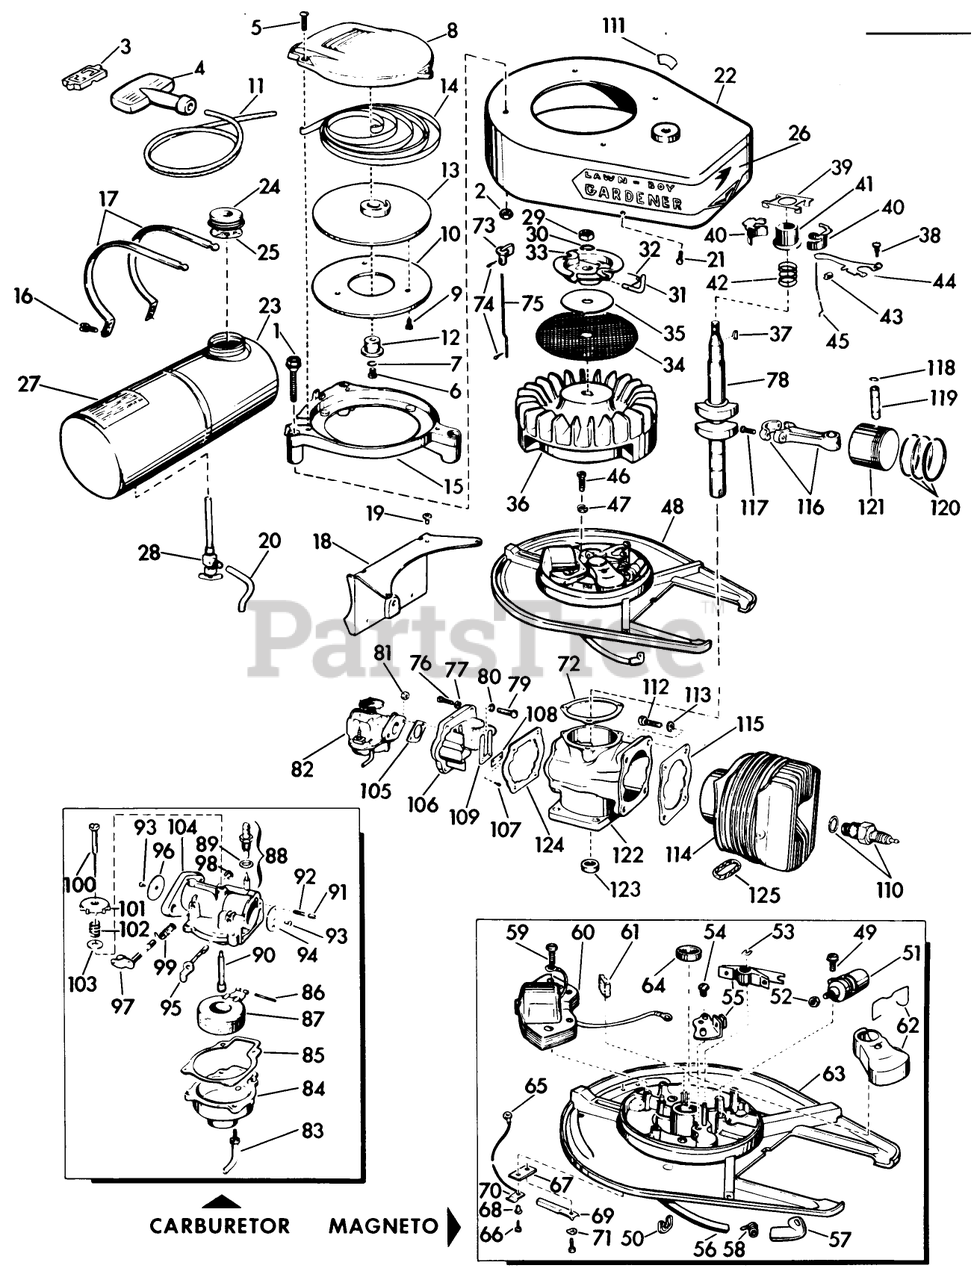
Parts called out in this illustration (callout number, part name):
10	Plate-Pulley
14	RECOIL SPRING
15	Base-Starter
21	SCREW S
24	Gas Cap
27	Decal-Instruction
28	VALVE&SCREEN SM
31	PIN - STARTER
41	COLLAR S
42	Spring-Governor
43	WEAR BLOCK S
44	GOVERNER LEVER AY
45	GOVERNOR ROD S
55	BREAKER AY. S
57	Cover-Rubber
66	Screw Shut-off Switch
71	Washer, Bow
72	GASKET S
73	KNOB, CHOKE BAR
74	Cotter Pin-Choke Knob
76	SCREW S
78	Crankshaft
81	STOP NUT
93	Screw-Choke Disc
99	SPRING
100	NEEDLE AY. S
102	Spring-Ndl. Adj.
105	GASKET S
108	PLATE-BACKUP, REED
110	Spark Plug
111	Decal-Off-on
117	Screw-Connecting Rod
124	GASKET
